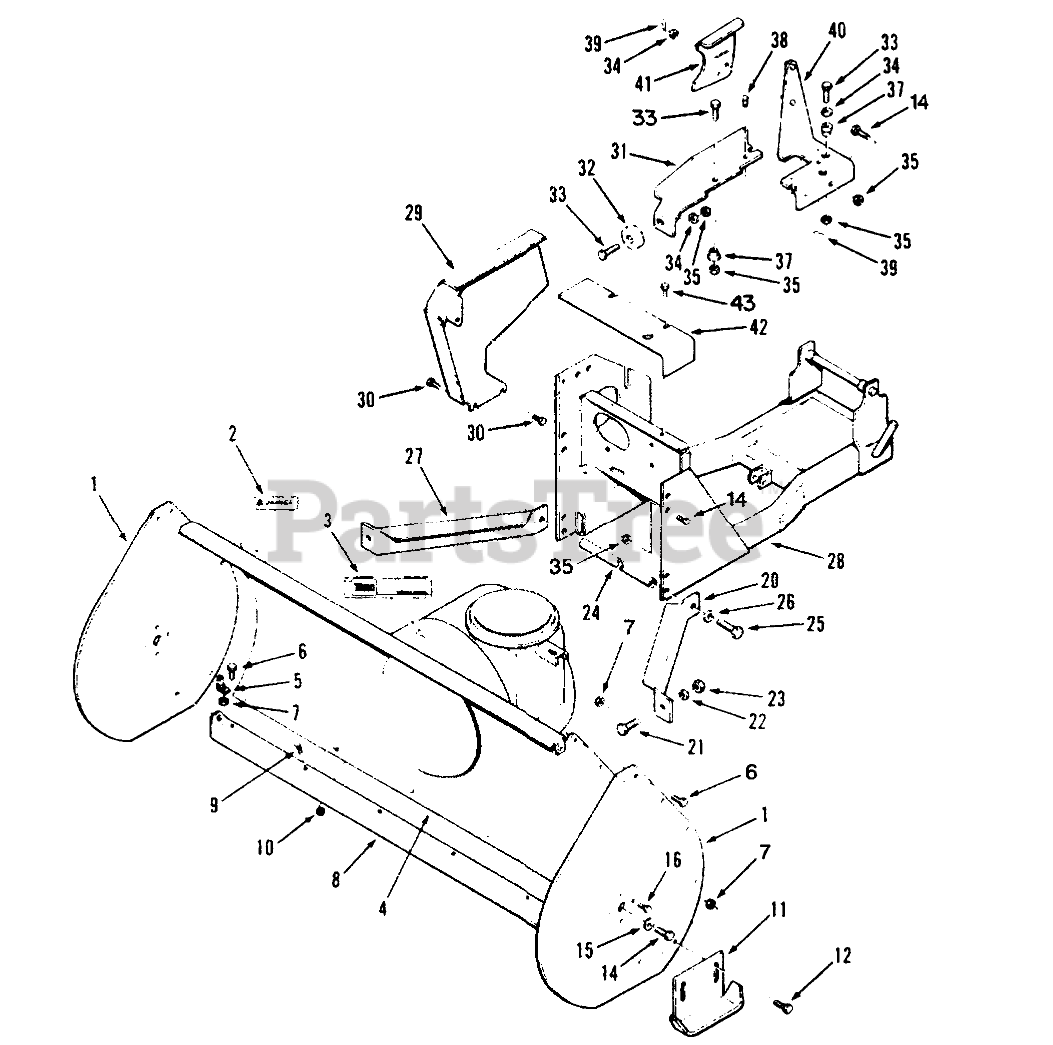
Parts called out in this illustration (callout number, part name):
1	Plate-Side
2	DECAL-WARNING, AUGER
3	DECAL - REAR FRAME
4	Housing-Auger (Incl. Ref. #2)
5	BLADE SUPPORT BRKT R
6	SCREW-HH
7	NUT-LOCK, NI
8	Blade-Scraper
9	SCREW-CARR
10	NUT-LOCK, NI
11	Skid
12	BOLT-CARR
14	SCREW-HH
15	WASHER
16	SCREW-HH
20	BRACE-L.H. R
21	SCREW-CARR
22	WASHER-FLAT
23	Nut
24	BRACE-CROSS R
25	SCREW-HH
26	WASHER-LOCK
27	BRACE-R.H. R
28	WLDMT-CARRIER FRA R
29	WLDMT-BELT COVER R
30	Bolt
31	BRACKET-BUMPER R
33	SCREW-HH
34	WASHER-FLAT
35	NUT-LOCK, NI
37	SPACER-LIFT LINK
38	CLEVIS PIN
39	Hairpin
40	WLDMT-BRKT GUARD R
41	GUARD-BELT R
42	GUARD R
43	Bolt
